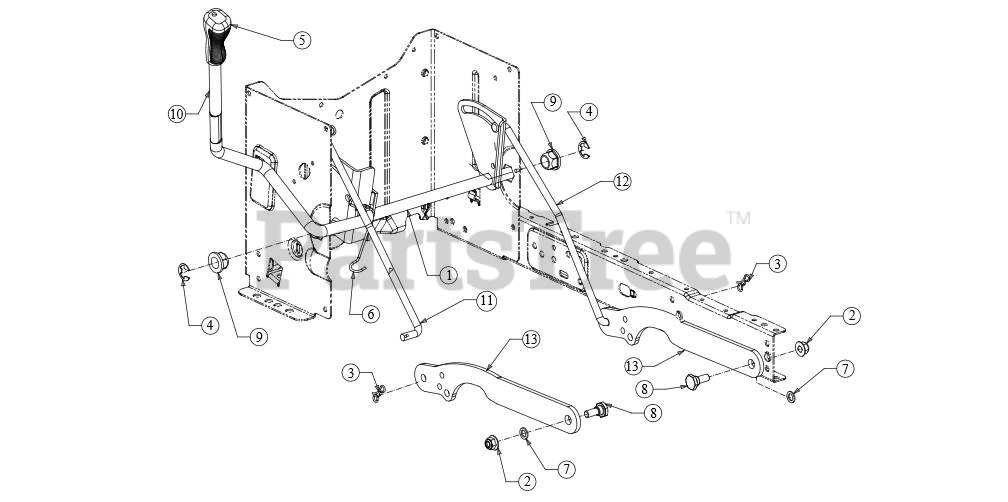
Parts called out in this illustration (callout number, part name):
1	LIFT SHAFT ASSEMBLY
3	PIN:COTTER
4	E-RING
6	TORSION SPRING
7	FLAT WASHER
8	SHOULDER SCREW
9	FLANGE BEARING
10	LIFT HANDLE
11	LIFT ROD (RH)
12	LIFT ROD (LH)
